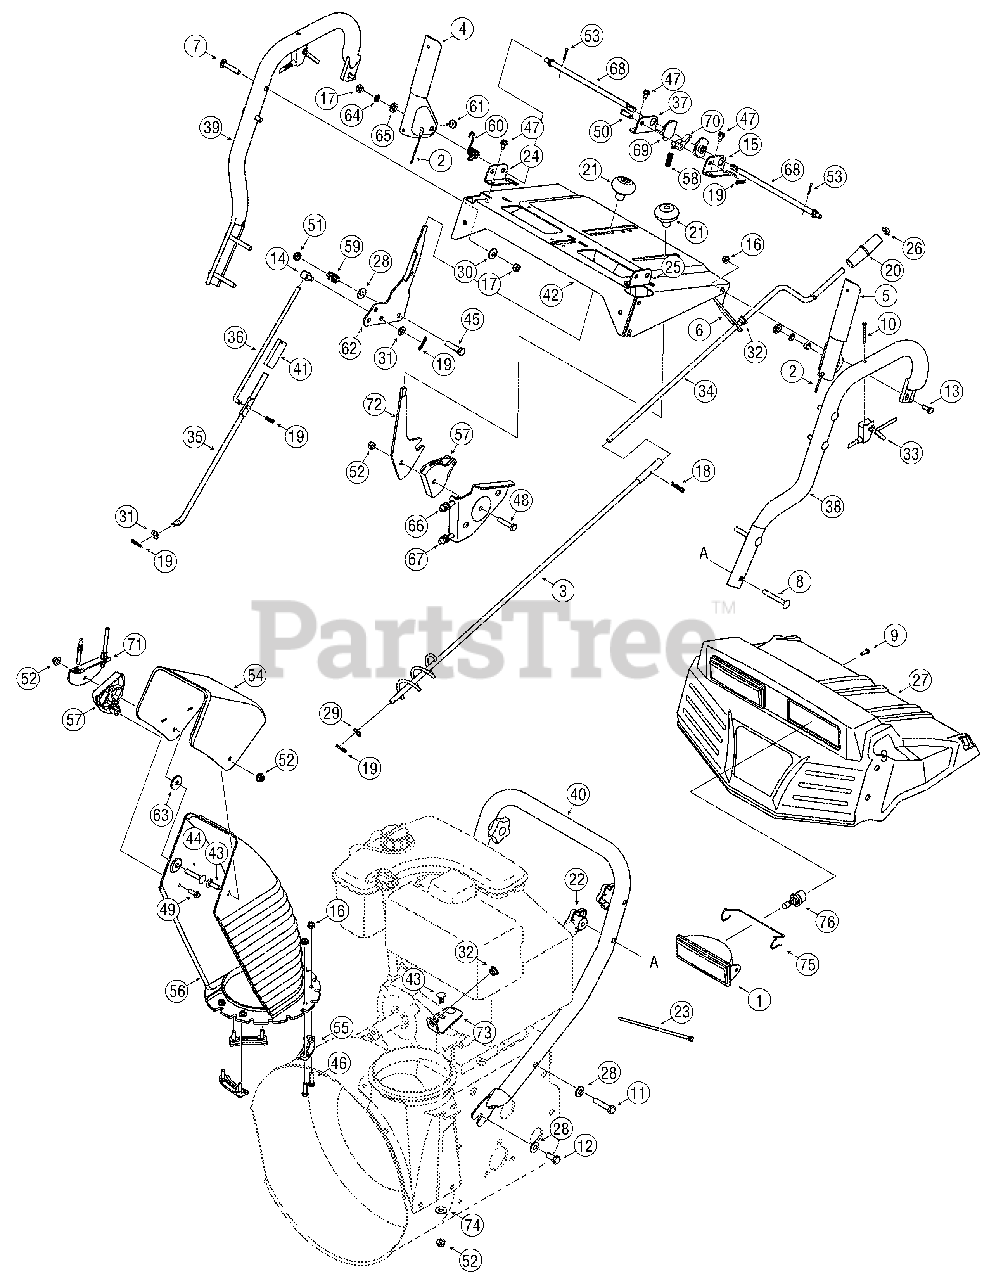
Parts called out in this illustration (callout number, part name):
1	Light Housing
2	Cable Assembly, Auger/Drive
5	Handle, Engage, LH
7	Screw, Carr., 5/16-18 x 1.75
8	Screw, Carr., 5/16-18 x 2.5
9	Screw, #10-16 x .625
10	Screw, #10-24 x 1.75
11	Screw, Hex, 3/8-16 x 1,75
12	Screw, Hex, 3/8-16 x .88
13	Screw, Hex, 1/4-20 x .75
14	Ferrule, 5/16-18 x .312 Dia
16	Nut, Hex Flange, 1/4-20
17	Nut, Hex, 5/16-18 GR5
18	Pin, Internal Cotter
19	Pin, Internal Cotter
20	Knob, Crank
21	Knob, Shift
22	Knob, Star, 5/16-18
23	Tie, Cable
26	Cap, Push, 3/8
27	Panel, Handle, Style 9
27	Graphic, Auger/Chute
27	Graphic, Chute Tilt
27	Graphic, Starting Instructions
28	Washer, Bell, .375 x .87 x .063
29	Washer, Flat, .375 x .738 x .063
30	Washer, Bell, .34 x .872 x .06
31	Washer, Flat, .344 x .688 x .065
32	Bushing, Plastic, .38 ID
33	Cable Assembly, Trigger
35	Rod, Lower Shift
36	Rod, Upper Shift
41	Connector, Shift Rod
43	Screw, Carriage, 5/16-18 x 1.0
44	Screw, Carriage, 5/16-18 x 1.75
45	Screw, Hex, 3/8-24 x 1.5
46	Screw, Hex, 1/4-20 x 1.0
47	Screw, Hx, 1/4-20 x .5
48	Screw, Hex, 5/16-18 x 1.5
49	Screw, Hx,1/4-15 x .75
50	Pin, Clevis, .312 x 1.0
51	Nut, Insert, 3/8-24
52	Nut, Flange Lock, 5/16-18
53	Pin, Cotter, 3/32 x .75
54	Chute, Upper, 6.0
54	Graphic, Danger
55	Flange Keeper, Chute
56	Chute, Lower
57	Cable Guide, Chute Tilt
58	Spring, Compression
59	Spring, Compression
60	Spring, Torsion
61	Bumper, Rubber
63	Washer, Flat, .344 x 1.125 x .12
64	Washer, Lock, 5/16
65	Washer, Flat, .35 x .72 x .134
66	Cable, Chute Control, 66"
67	Cable, Chute Control w/Clip
69	Cam, Handle Lock
70	Pawl, Handle Lock
74	Washer, Flat, .349 x .879 x .063
75	Headlight Retainer
76	Halogen Lamp
